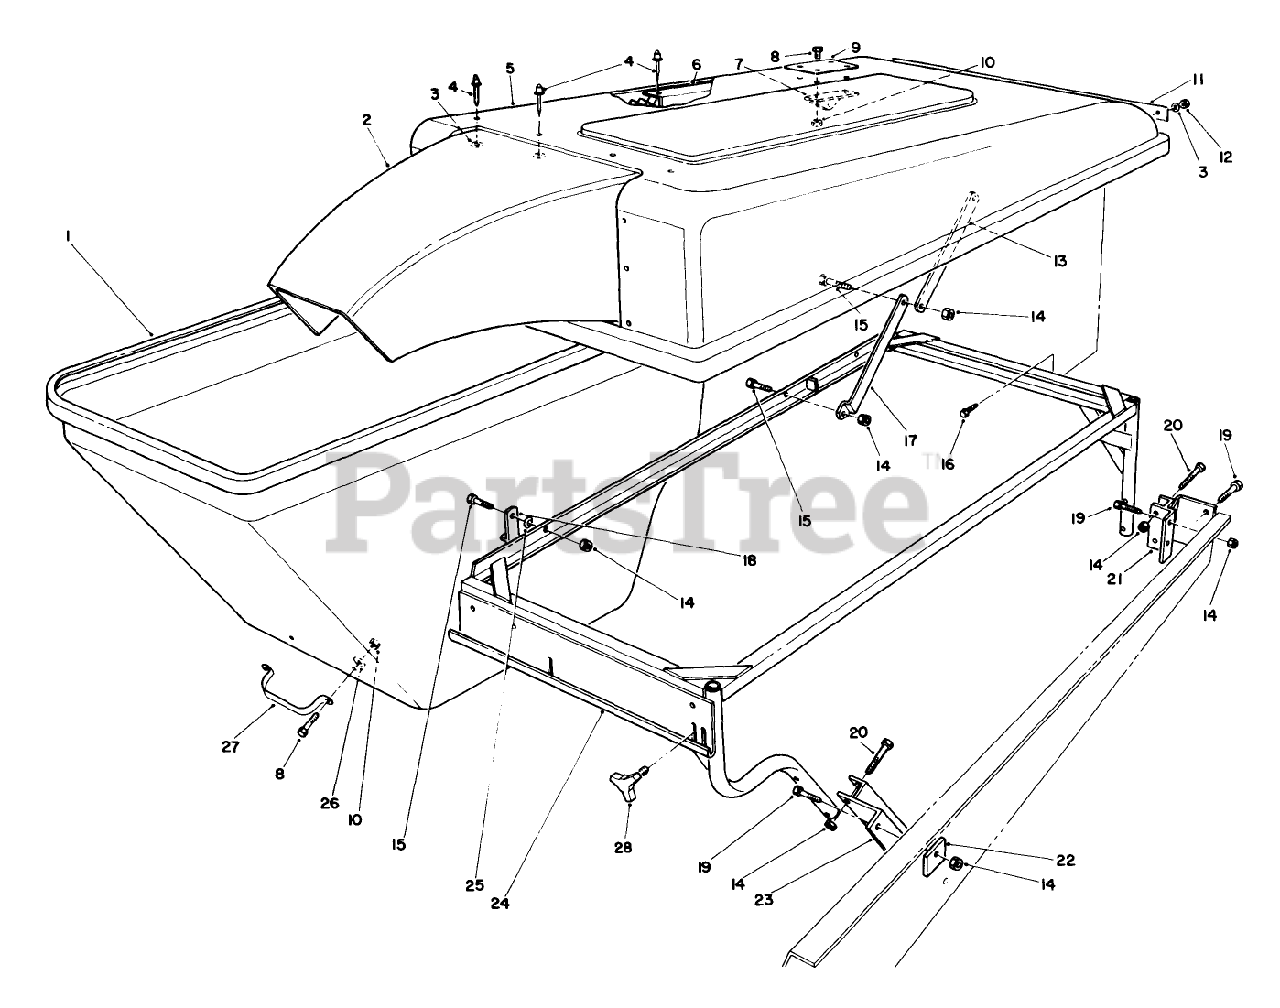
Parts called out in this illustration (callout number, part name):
1	BAGGER HOPPER
2	BAGGER SNOUT
3	WASHER-FLAT
4	RIVET-POP
5	Hood-Bagger
6	Bagger Screen
7	Pivot
8	SCREW-HH
9	HOOD PLATE
10	NUT-LOCK, NI
11	HINGE PLATE
12	NUT-LOCK, NI
13	Link
14	NUT-LOCK, NI
15	SCREW-HH
17	Link-Bag
18	Latch-Hopper
19	SCREW-HH
20	SCREW-HH
21	Bracket-Rear
22	Plate-Reinforcing
23	Bracket-Front
24	HOPPER FRAME WA
25	WASHER-SPRING
26	WASHER-FLAT
27	Handle
